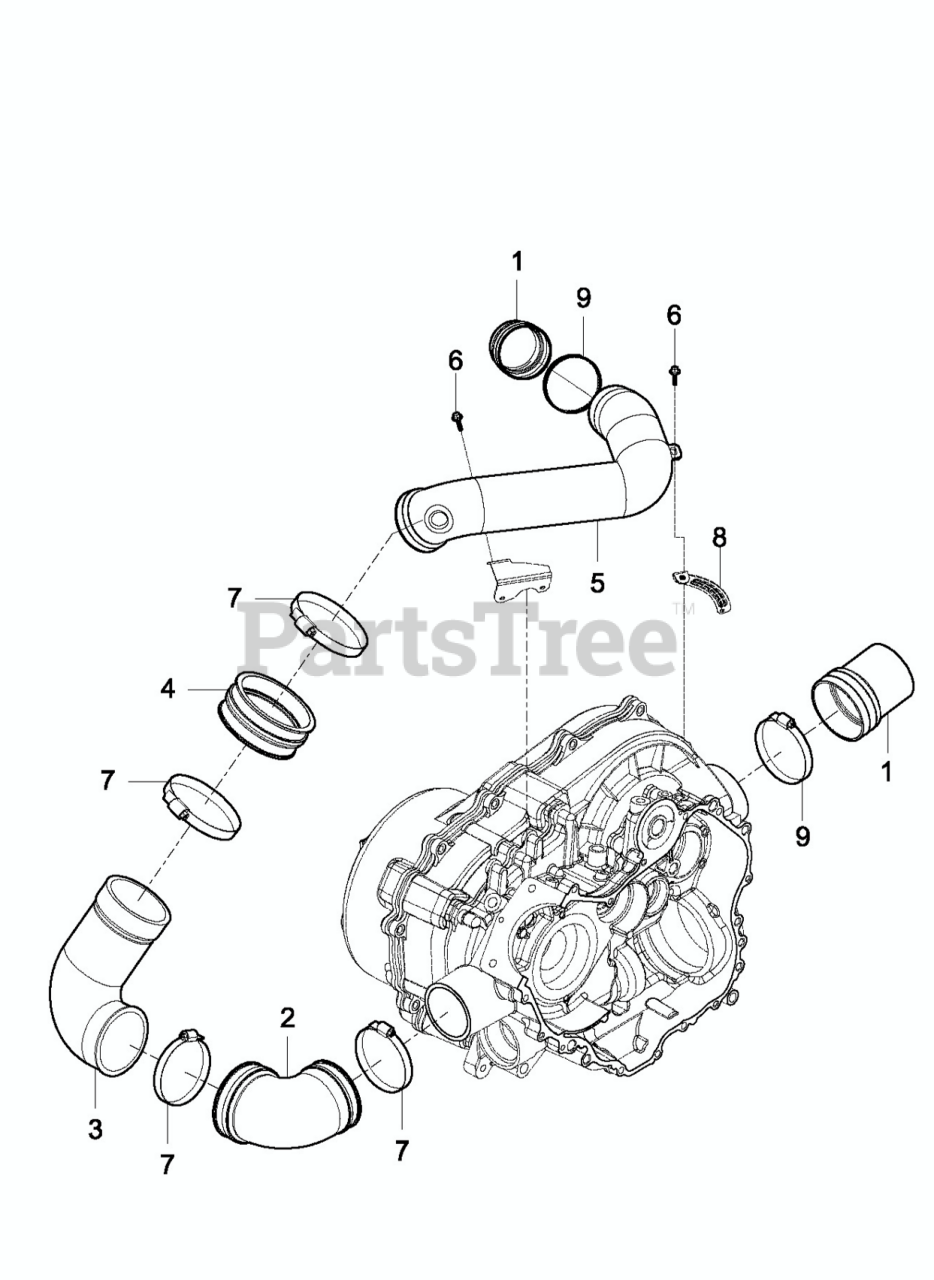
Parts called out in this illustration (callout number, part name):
1	CLUTCH AIR OUTLET SLEEVE
2	CLUTCH AIR INLET SLEEVE
3	CLUTCH AIR INLET DUCT
4	CLUTCH AIR INLET SLEEVE
5	CVT INLET DUCT
6	HEXAGON FLANGE BOLT M6X16
7	NARROW BAND CLAMP
8	AIR DUCT BRACKET
9	SCREW HOOP
